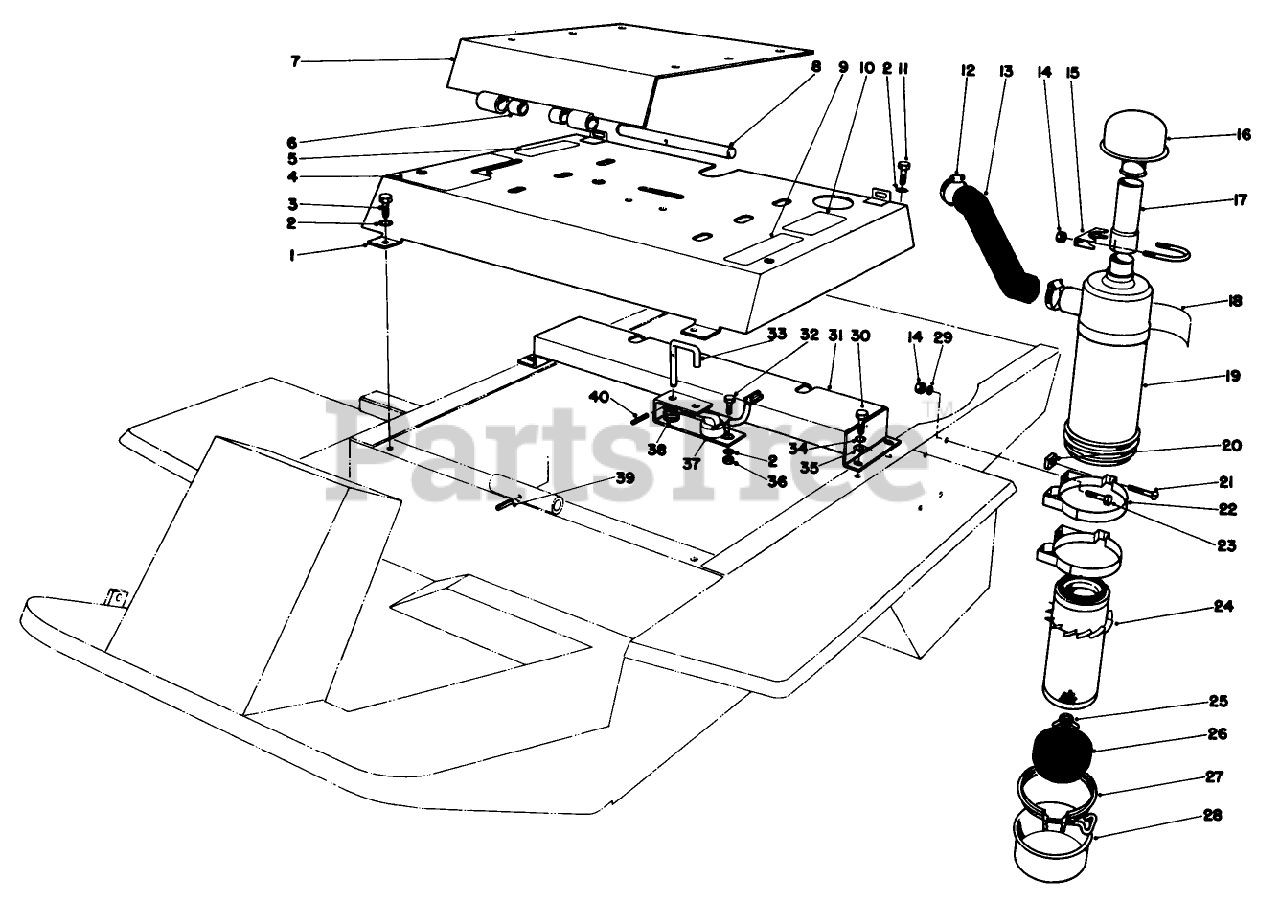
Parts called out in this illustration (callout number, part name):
2	SCREW-HH
3	SCREW THD 1/4 20 5/8
6	.503ID X .875LG BSHG
7	SEAT MTG WA
8	SHAFT-PIVOT, SEAT
10	DECAL-REFUELING
11	SCREW-HH
12	CLAMP-HOSE
14	NUT-HEX
15	CLAMP-MUFFLER
18	DECAL-INSTALLATION
19	AIR CLEANER ASM
20	NUT-SQUARE
21	SCREW
22	MOUNTING BAND ASM
23	SCREW-HH
25	NUT AND GASKET ASM
26	SKIRT-BAFFLE
27	CLAMP ASM
28	A/C CUP ASM
29	SCREW-HH
30	SCREW-HH
32	SCREW-HH
34	WASHER-LOCK
35	WASHER-FLAT
36	NUT-HEX
38	SPRING
39	SCREW-HH
40	PIN-SPRING
